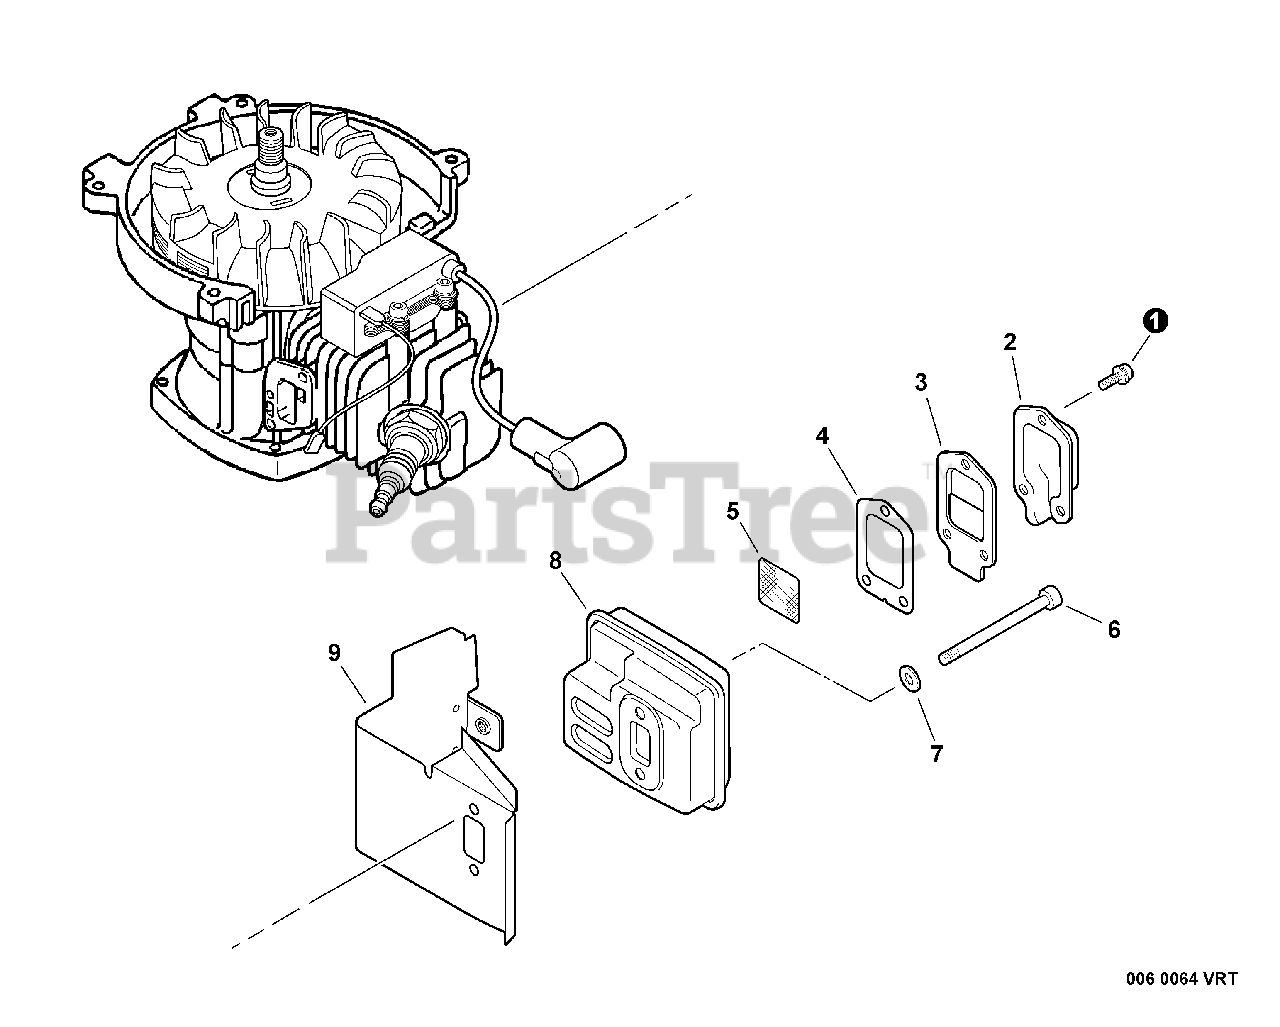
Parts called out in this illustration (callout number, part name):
1	SCREW 4×10
2	GUIDE, EXHAUST - INNER
3	GUIDE, EXHAUST
4	GASKET, EXHAUST
5	SCREEN, SPARK ARRESTER
6	BOLT M5×50
7	WASHER, FLAT 5.5×10×0.8
9	HEAT SHIELD, EXHAUST
